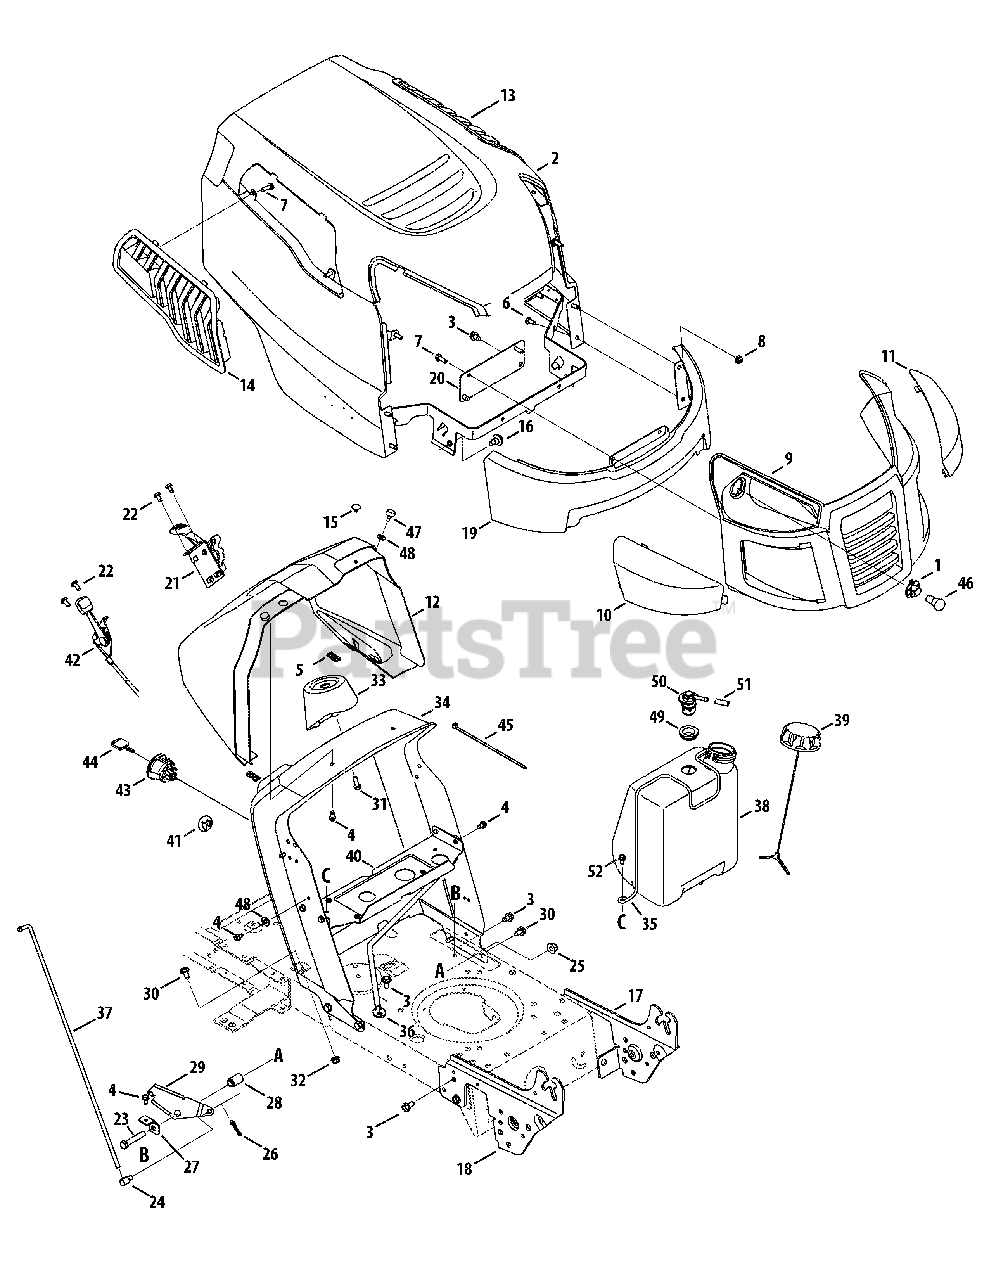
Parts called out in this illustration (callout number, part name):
1	Bulb Socket
2	Hood Assembly
3	Screw, 5/16-18 x .750
4	Hex Washer Screw, 1/4-20 x .500
5	Tin Clip Nut, 1/4-20
6	Hex Screw, 1/4-20 x .620
7	Screw, 1/4 x .750
8	Nut, Hex Flange Insert Lock, 1/4-20
10	Headlight Lens, RH
11	Headlight Lens, LH
12	Dash Collar
13	Hood Scoop, LH
14	Hood Scoop, RH
15	Bumper
16	Shoulder Screw, 5/16-18
17	Left Support Pivot Bracket
18	Right Support Pivot Bracket
19	Lower Grill
20	Lower Grill Bracket
21	Speed Selector
22	Self-Tap Screw, 1/4-20
23	Hex Head Screw, 3/8-16
24	Ferrule, 1/4-20 x 1.00
25	Nut, Hex Flange Insert Lock, 3/8-16
26	Cotter Pin
27	Speed Latch Support Tab
28	Flange Spacer
29	Speed latch
30	Self-Tap Screw, 5/16-18
31	Hex Screw, 1/4 x .750
32	Nut, Hex Flange Lock, 5/16-18
33	Steering Support
35	Fuel Tank Support Rod
36	Dash support Rod
37	Speed Selector Control Rod
38	Fuel Tank
39	Fuel Cap
40	Gas Tank Support Bracket
41	Choke Plug
42	Throttle/Choke Assembly
43	Key Switch Module
44	Key (2 pack)
45	Cable Tie
46	Headlight Bulb
47	Ratchet Clip, .250 x .500
48	Flat Washer, .25 x .630 x .0515
49	Rubber Grommet
50	Fuel Rollover Valve
51	Vent Hose
52	Hex Washer Screw, 1/4-20 x .625
